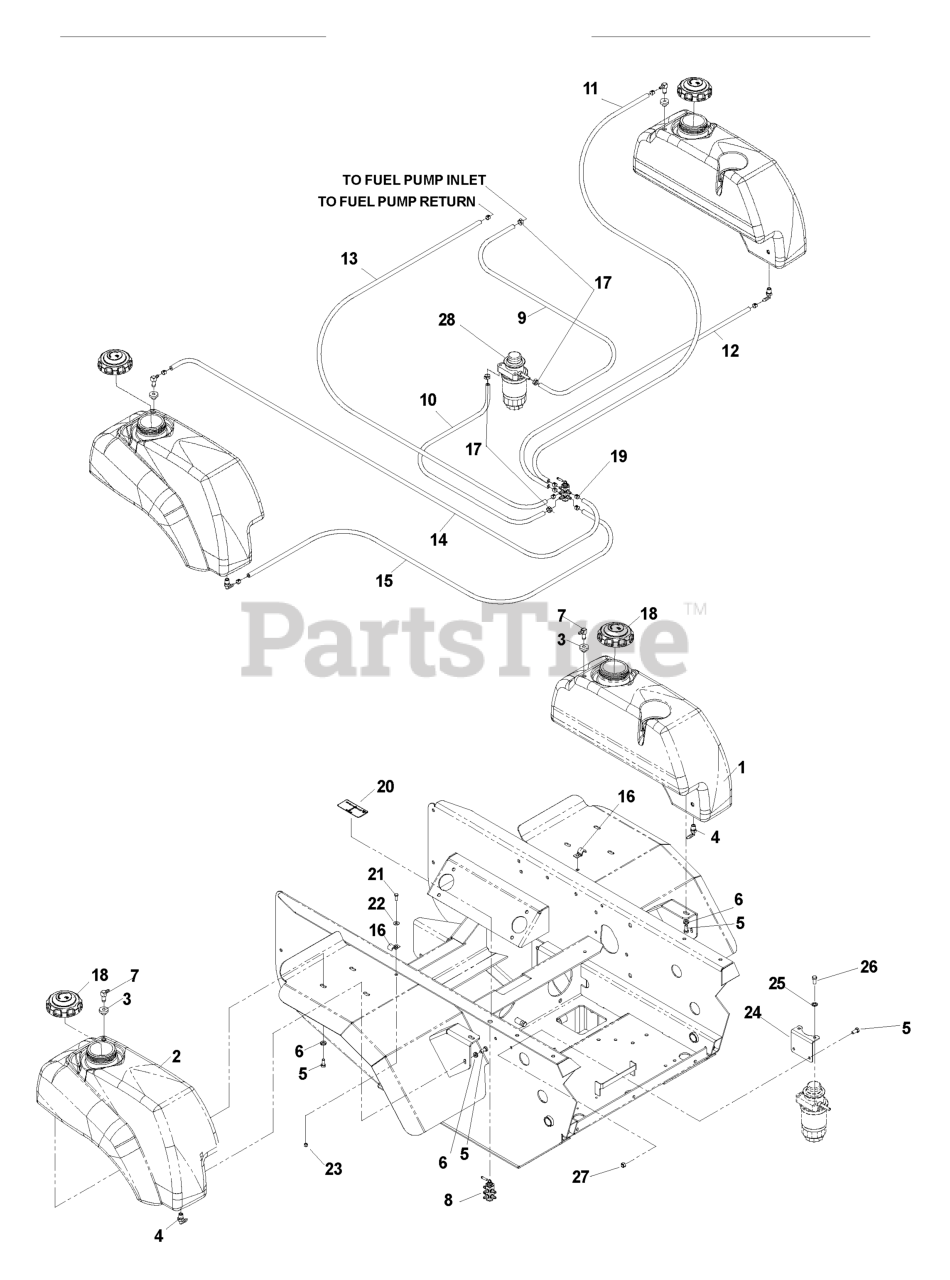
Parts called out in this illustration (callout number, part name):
1	FUEL TANK DIESEL LT
2	FUEL TANK DIESEL RT
3	RUBBER GROMMET
4	HOSE BARB 90 DEGREE
5	HCS 5/16C X 3/4
8	FUEL VALVE
9	FUEL LINE 38"
10	FUEL LINE 35"
11	FUEL LINE 79"
12	FUEL LINE 57"
13	FUEL LINE 54"
14	FUEL LINE 34"
15	FUEL LINE 13"
18	TANK CAP - DIESEL
19	HOSE CLAMP
20	FUEL VALVE DECAL
21	HCS 1/4C X 3/4 HCS
22	WASHER 1/4 FLAT
23	NUT.1/4-20.HEX.NYLOC.ZD
24	MOUNTING BRACKET
25	WASHER.LOCK.HVY.HLCL.SPR.5/16
27	NUT 5/16 NYLOC
28	FUEL FILTRATION SYSTEM
